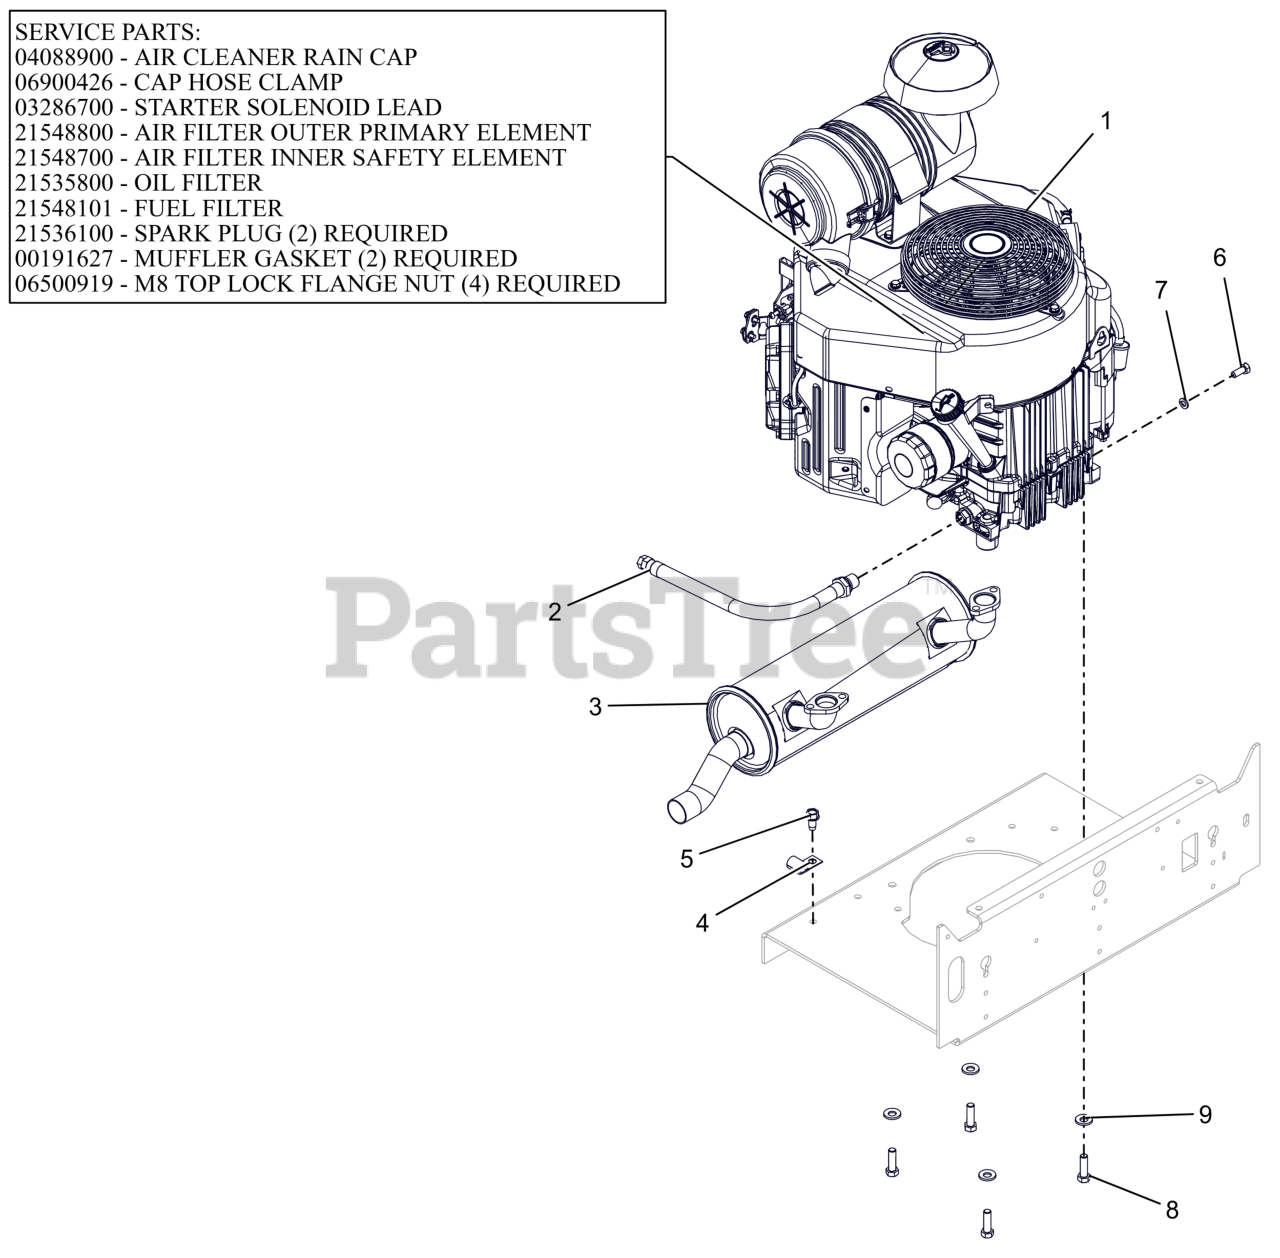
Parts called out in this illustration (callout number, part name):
1	ENGINE, KAWASAKI FX691
2	HOSE, OIL DRAIN
3	MUFFLER, KAW FX691/730
5	SCR,TAP .375-16X.75 HWH TR ZCC
6	BLT, HEX M8-1.25X20 G8.8 ZCC
7	WSHR,LK-REG .312X.078 ZCC
8	BLT, HEX .38-16X1.25 G5 ZCC NT
9	WASHER, 3/8" SPRING DISC
